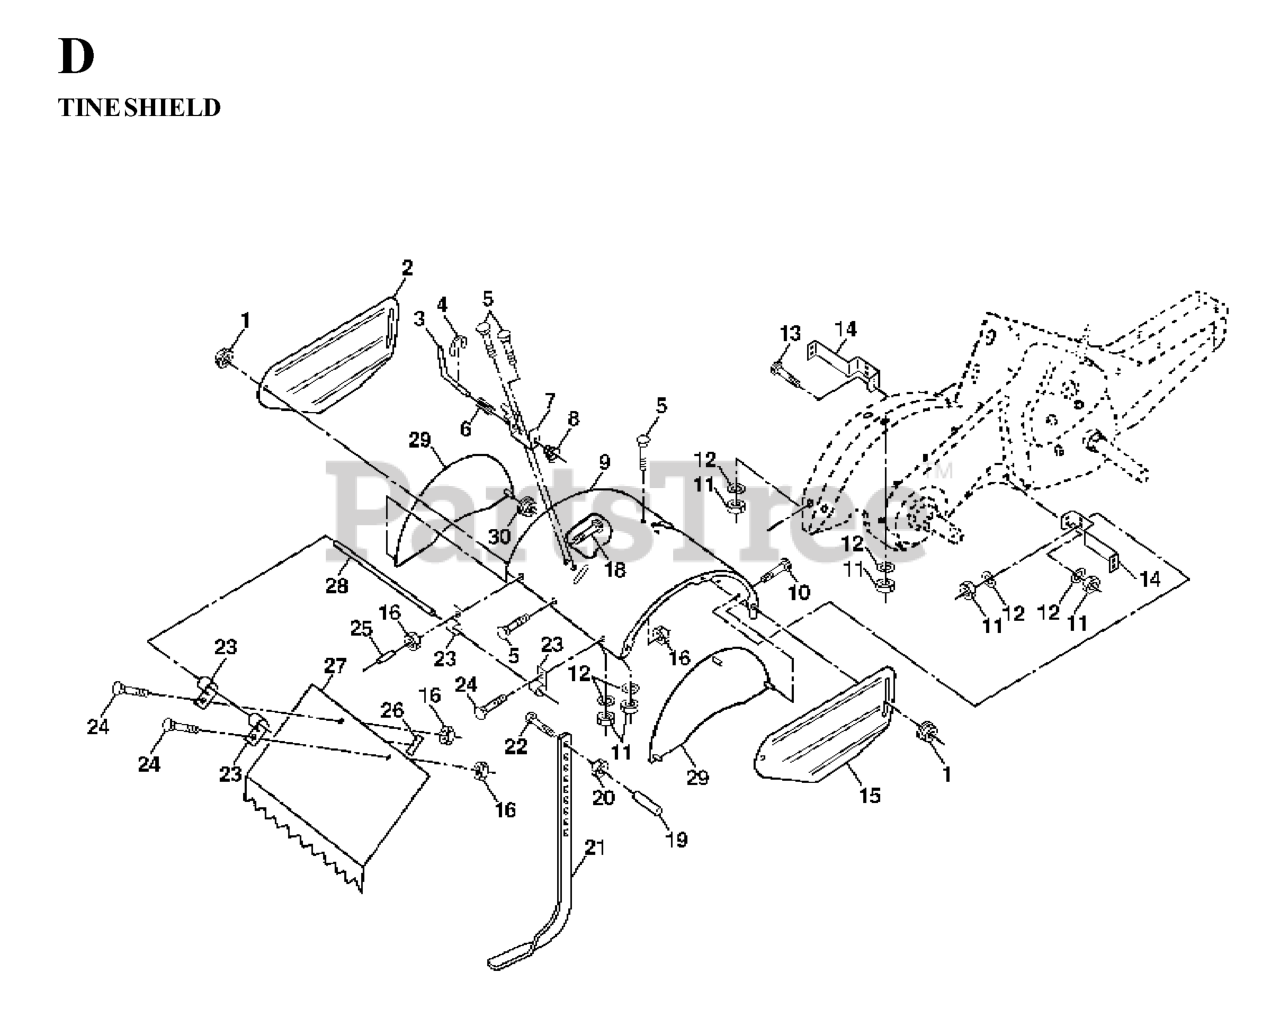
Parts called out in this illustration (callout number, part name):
1	NUT
2	SHIELD
3	STAKE PIN TI
4	KLIP RING TI
5	RP BOLT 5/16-18 X3/4 ZN/YEL GR
7	BRACKET.LATCH.STAKE.3.20.BLACK
8	SPRING CRT
9	SHIELD
12	WASHER.LOCK.HVY.HLCL.SPR.5/16
13	BOLT.CARRIAGE.5/16-18
14	BRACKET.TINE.SHIELD.TILLER.BLA
15	SIDE SHIELD RH
16	NUT
20	NUT.HEX.3/8-16UNC
21	STAKE.DEPTH.16.CRT.BLACK
22	BOLT.375-16
25	VINYL CAP TI
26	PAD IDLER TI
27	SHIELD LEVELING
28	PIN.HINGE.TILLER
29	SIDE SHIELD
30	LOCKNUT-FLANGE 5/16-18
